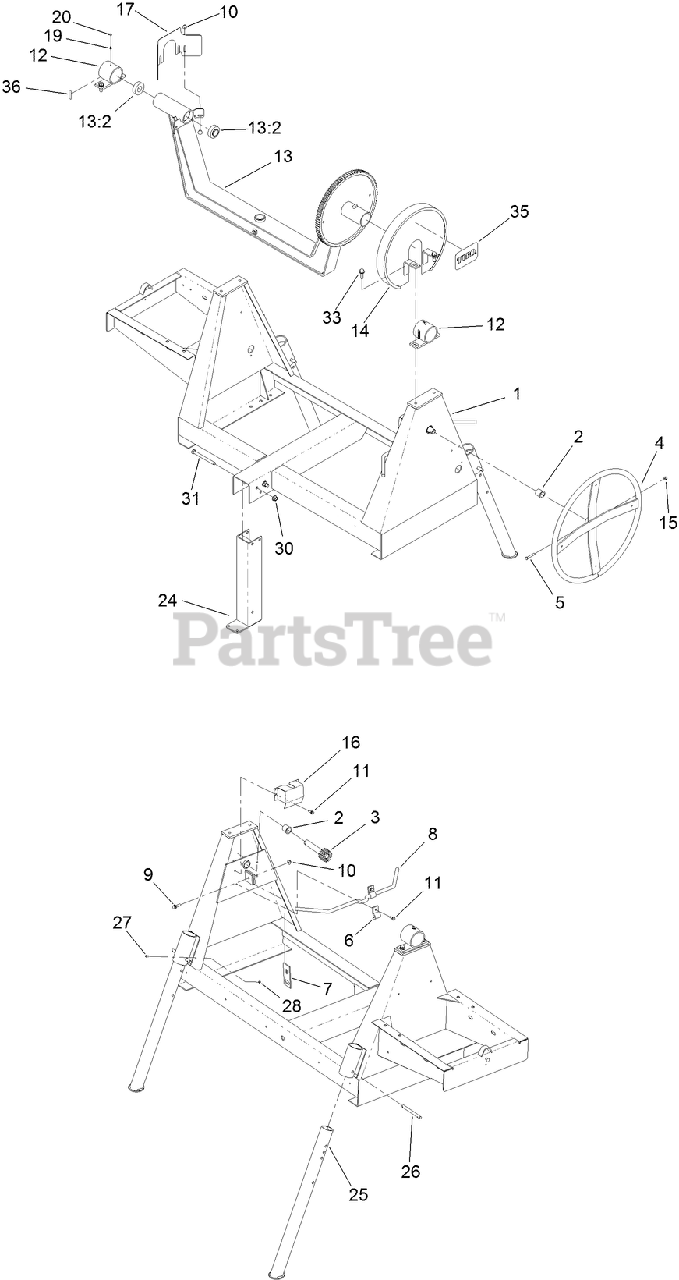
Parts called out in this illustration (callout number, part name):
2	BUSHING-NYLON
3	SHAFT-TILT
4	HANDWHEEL
5	SCREW-HH
6	BRACKET-HANDLE
7	DOG-BRAKE
8	HANDLE-BRAKE
9	SCREW-HHF
10	NUT-HF, NI
11	SCREW-THD ROLL, HWH
12	TRUNNION
13	YOKE ASM
13:2	BEARING
14	GUARD-BRAKE, UPPER
15	NUT-LOCK, NI
16	GUARD-BRAKE, LOWER
17	GUARD-PINION
19	FITTING-GREASE
20	CAP-PLUG
24	POST-FOOT
25	LEG-STABILIZER
26	PIN-CLEVIS, LANYARD
27	SCREW-PPH
28	NUT-LOCK, NI
30	NUT-LOCK
31	SCREW-HH
33	SCREW-HWH
35	DECAL
36	DECAL-GREASE
